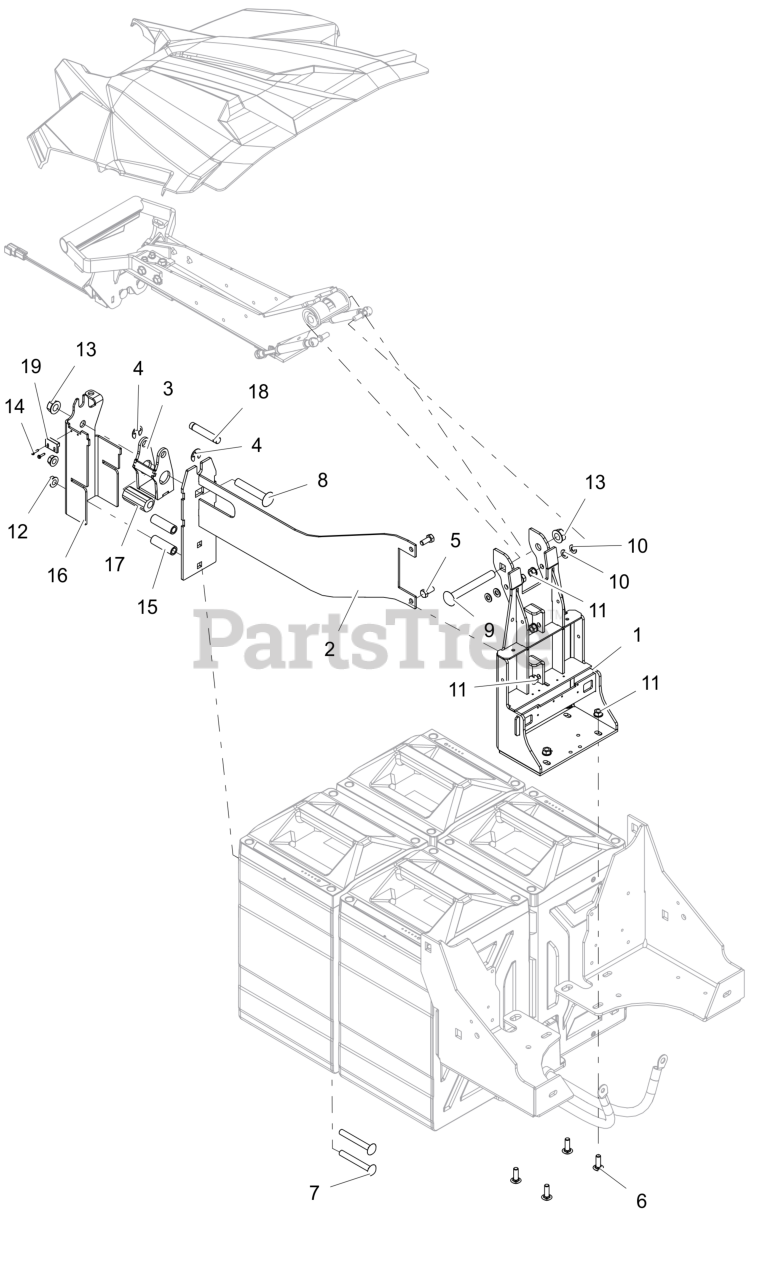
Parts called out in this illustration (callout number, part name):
1	WLDMT, BATTERY HOLDDOWN PIVOT (ORANGE)
2	WLDMT, ECCENTRIC MTG (ORANGE)
3	WLDMT, ECCENTRIC
4	RG-RTNG-EXT .438X.035
5	BLT,HEX .31-18X.75 G5 ZCC
6	BLT,RHSSN .31-18X1.00 G5 ZCC
7	BTL,RHSSN .375-16 X 3 G5 ZCC
8	BTL,RHSSN .500-13 X 3 G5 ZCC
9	BTL,RHSSN .500-13 X 4.25 G5 ZCC
10	WSHR,FLT .323X.625X.062 ZCC
11	NUT,LK-CTR-FLG .31-18 GF ZCC
12	NUT-LK-CTR-FLG .375-16 GF ZCC
13	NUT-LK-CTR-FLG .500-13 GG ZCC
14	SCR-TAP #4-40x.50 HWH ZCC
15	SPCR, LATCH BRKT (BLACK)
16	BRKT, ECCENTRIC MTG (ORANGE)
17	ECCENTRIC, HOOD LATCH
18	ROD, LATCHING
19	SWITCH, MAGNET (NO WIRE)
